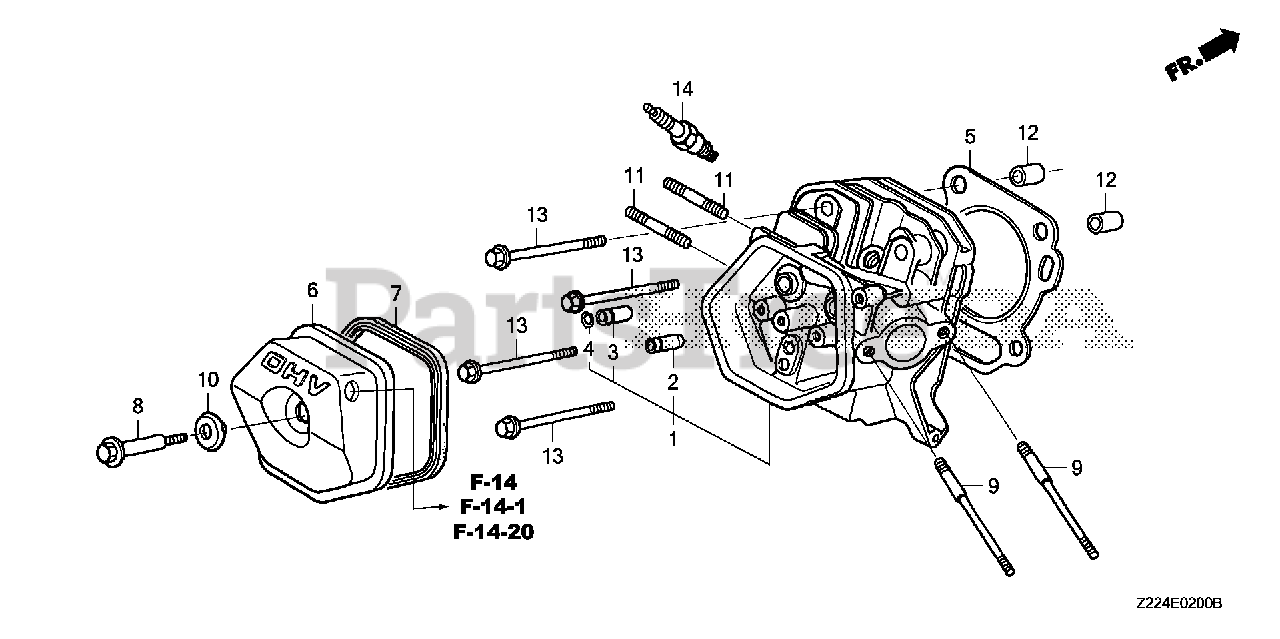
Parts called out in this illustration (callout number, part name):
1	CYLINDER HEAD
2	GUIDE, VALVE (OS)
3	GUIDE, EX. VALVE (OS)
4	CLIP, VALVE GUIDE
5	GASKET, CYLINDER HEAD
6	COVER, HEAD
7	GASKET, CYLINDER HEAD COVER
8	BOLT, HEAD COVER
9	BOLT, STUD (8X115)
10	WASHER, HEAD COVER
11	BOLT 2, STUD (8X32)
12	PIN A, DOWEL (12X20)
13	BOLT, FLANGE (10X80)
14	SPARK PLUG (BPR5ES) (NGK)
